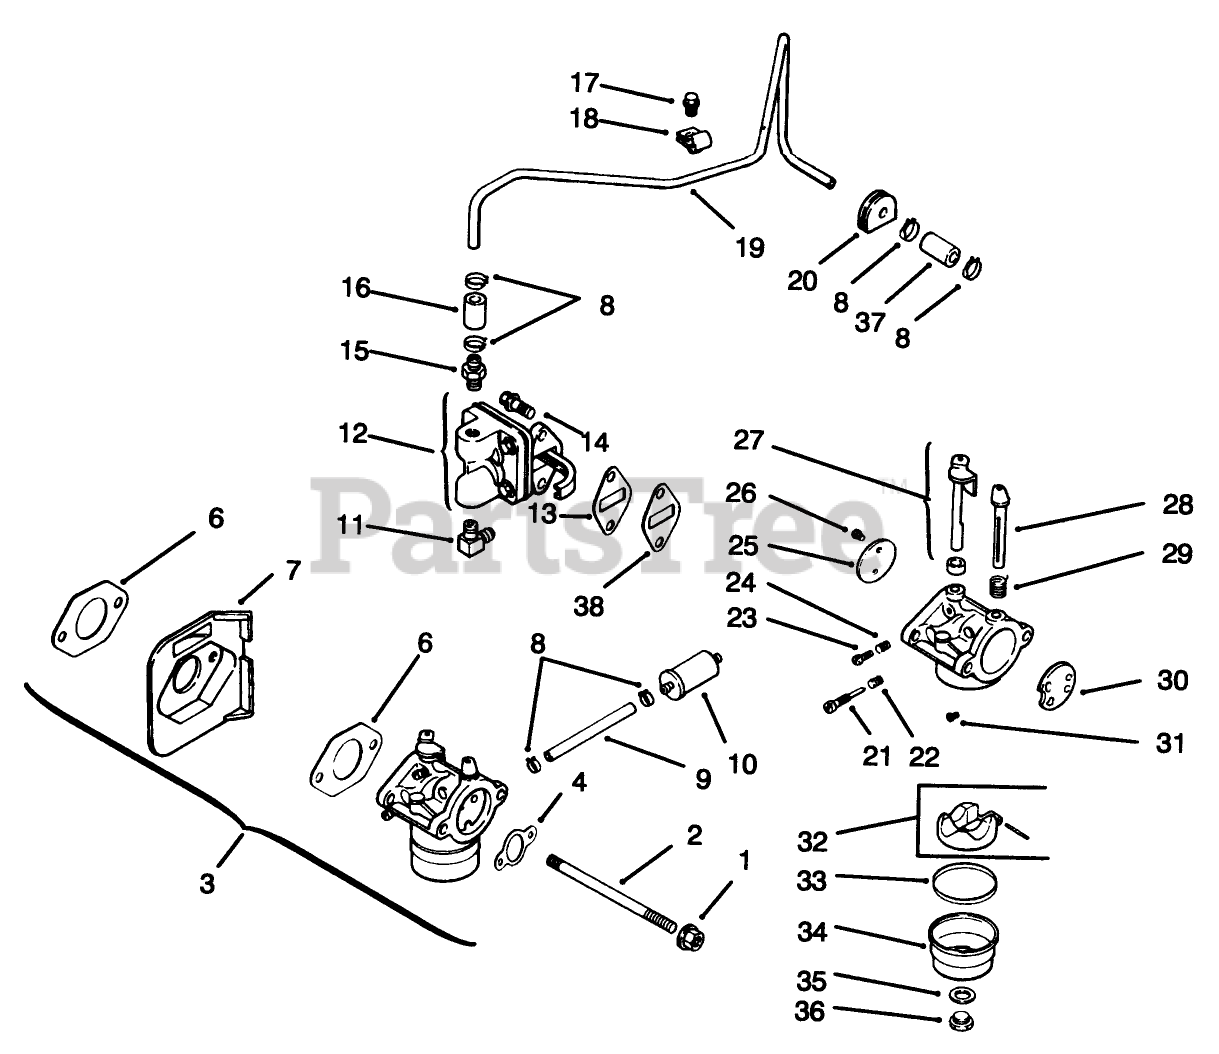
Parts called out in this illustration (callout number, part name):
2	Stud M6x1.0x110 (Only On: 72042,72043,72062,72063)
4	Gasket-Air Cleaner (Only On: 72042, 72043, 72062, 72063)
5	Carurator ASM Incl 21-36
6	Gasket-Carburetor (Only On: 72042, 72063, 72062, 72043)
7	Deflector-Heat
8	Clamp
9	Line-Fuel
10	Filter-Fuel (Only On: 72042,72043,72062,72063)
11	Connector
12	Kit-Pump INCL 13-14 (Only On: 72042,72043,72062,72063)
13	Gasket-Fuel Pump (Only On: 72042,72043,72062,72063)
14	Screw
15	Connector
16	Line-Fuel 1.25 Inch (Only On: 72042,72043,72062,72063)
18	Clamp-Fuel Line (Only On: 72042, 72063, 72062, 72043)
19	Line-Fuel
20	Grommet (Only On: 72042, 72063, 72062, 72043)
21	Needle-Idle Fuel Adjust
22	Spring-Idle Fuel (Only On: 72042, 72063, 72062, 72043)
23	Screw-Idle Speed Adjust (Only On: 72042,72043,72062,72063)
24	Spring-Idle Fuel (Only On: 72042, 72063, 72062, 72043)
25	Plate-Throttle (Only On: 72042,72043,72062,72063)
26	Screw-Throttle Plate (Only On: 72042,72043,72062,72063)
27	Shaft-W/Lever Seal (Only On: 72042, 72063, 72062, 72043)
28	Shaft-Choke (Only On: 72042. 72063, 72062, 72043)
29	Spring-Choke Return (Only On: 72042,72063, 72062, 72043)
30	Plate-Choke (Only On: 72042, 72063, 72062, 72043)
31	Jet-Main
32	Kit-Float (Only On: 72042,72043,72062,72063)
33	Gasket-Bowl (Only On: 72042,72043,72062,72063)
34	Bowl-Fuel (Only On: 72042, 72063, 72062, 72043)
35	Gasket-Bowl Screw (Only On: 72042, 72063, 72062, 72043)
36	Screw-Fuel Bowl (Only On: 72042, 72063,72062, 72043)
37	Line-Fuel 3" (Only On: 72042, 72063, 72062, 72043)
38	Spacer-Fuel Pump
